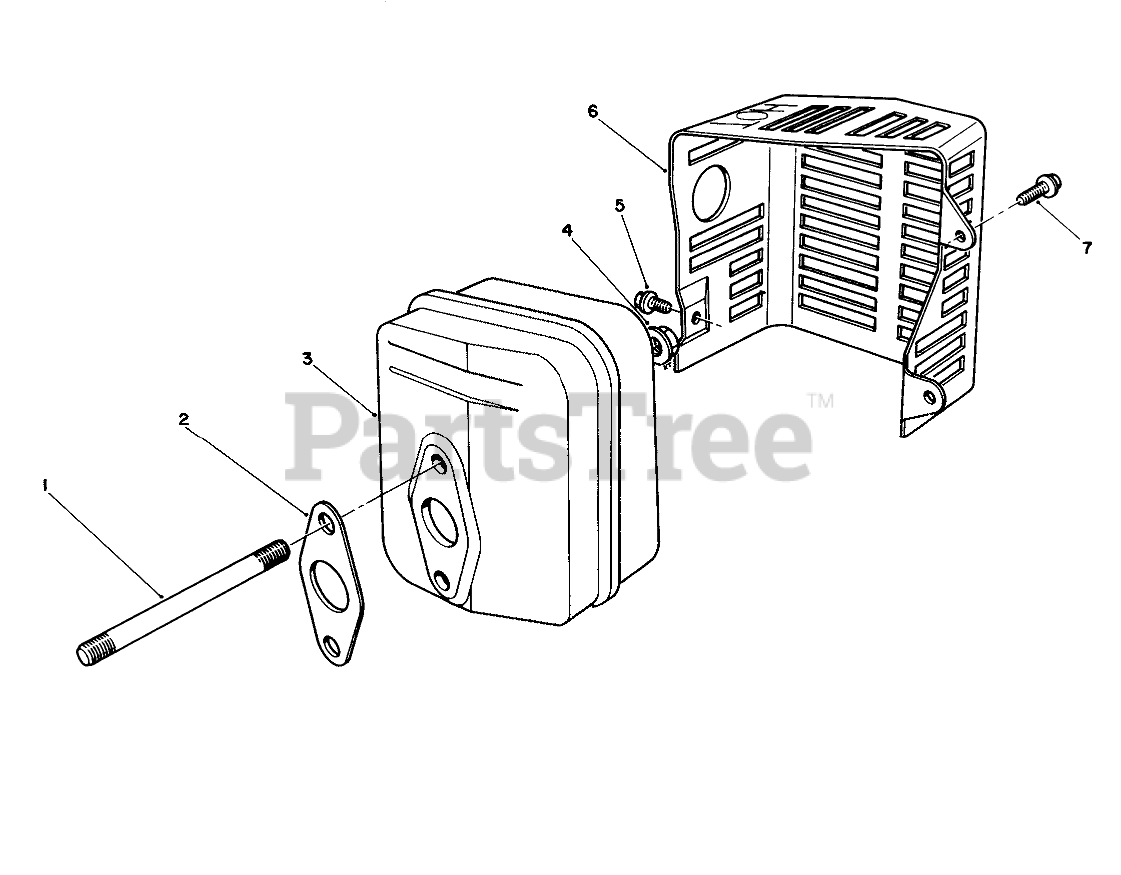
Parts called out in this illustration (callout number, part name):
2	GASKET
3	MUFFLER
5	SCREW
6	COVER
